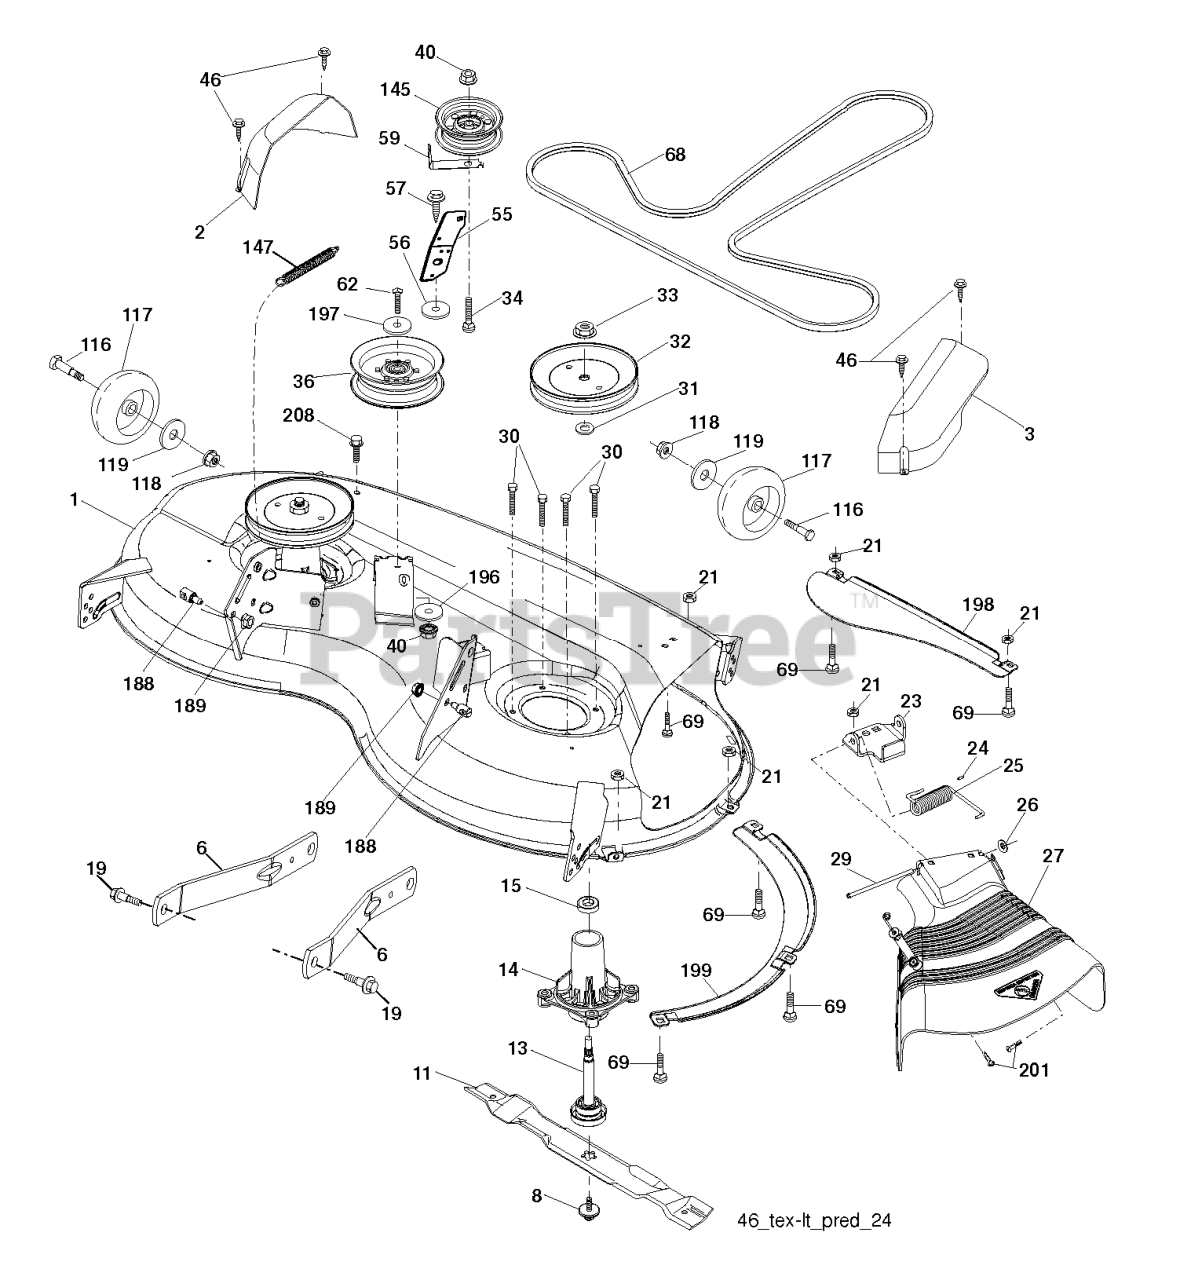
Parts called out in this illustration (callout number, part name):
1	DECK.WELDMENT.46"
2	COVER.MANDREL.LH.46"
3	COVER.MANDREL.RH.46"
6	ARM.SUSPENSION.MOWER.R
8	BOLT.WASHER.ASM.7/16-2
11	BLADE.MOWER.46".HI.LIFT
13	SHAFT.ASM.MDRL.N/GREASE.38
14	RP.HOUSING.MANDREL.4PT.
19	BOLT.SHOULDER
21	LOCKNUT
23	BRKT.DEFLECTOR.38"2005+
24	CAP-SLEEVE LT
25	SPRING.TORSION.DEFLECT
26	NUT PUSH M
27	SHIELD.DEFLECTOR.MOWER.46"BLAC
29	ROD.HINGE
30	SCREW, WASHER HEAD
31	WASHER.SPACER.MANDREL
32	PULLEY.MANDREL.5.438.PD
33	NUT.FLANGE.LOCK.TOP
34	BOLT.3/8-16X1.50
36	PULLEY.IDLER.2006
40	NUT LOCK FLG 3/8-16 UNC
46	SCREW.1/4-20X5/8
55	IDLER.ARM
56	SPACER.RETAINER
57	SCREW 3/8-16X1
59	GUARD, BELT
62	BOLT-HEX EAK
68	V-BELT
69	BOLT
116	BOLT M
117	WHEEL.GAGE.HALF.SPOKED
118	LOCKNUT
119	WASHER.5/16.FLAT.STE.STD.
145	PULLEY.IDLER.48"PRIMARY
147	SPRING.MOWER.DRIVE.ELECTRIC
188	STUD.FASTNER.W/ANTI-ROTATE
189	NUT LOCK HEX FLANGE 5/16-18
196	WASHER.13/32 X 1 X 1/2.11GUARD
197	WASHER
198	BAFFLE CENTER FRONT
199	BAFFLE FRONT RH
208	SCREW 3/8-16X1/2
240	BOLT-HEX EAK
